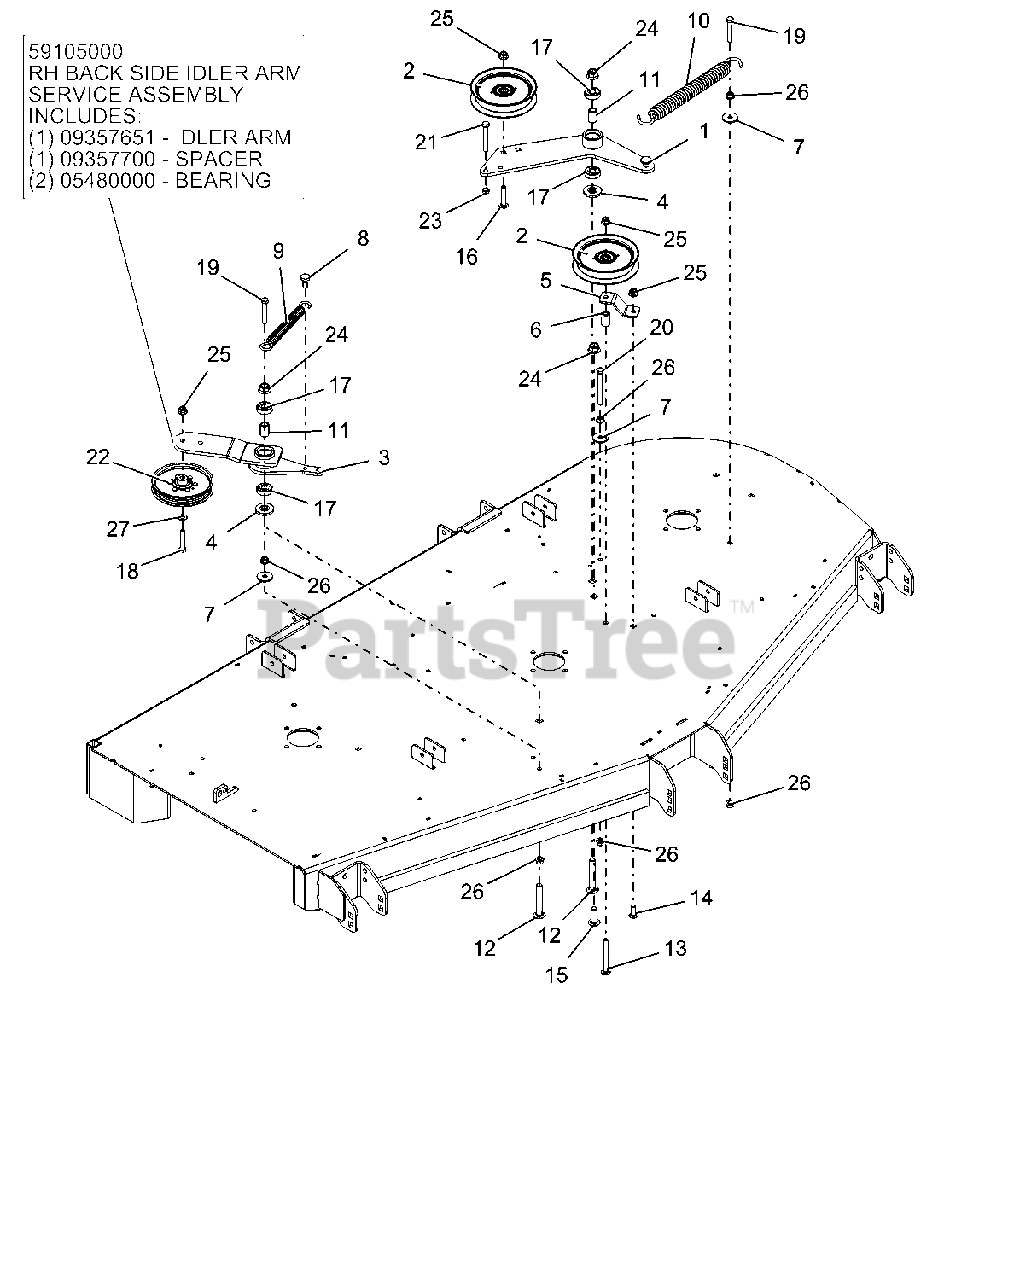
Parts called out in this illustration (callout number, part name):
1	DECK PTO IDLER ARM WLDMT - BLK
2	IDLER, FLAT 5.00"
3	BRG-BALL .50X1.38X.438 SEALED
3	SPACER .510 X .75 X 1.1485
3	DECK RH IDLER ARM WMT - BLK
3	RH BACKSIDE IDLER ARM ASSEMBLY
4	SPACER, IDLER ARM
5	PTO FIXED IDLER MTG BRKT -RED
6	BUSHING, SLV .380X.750X1.190
7	WSHR-FL-STL .406X1.375X.135 YZ
8	BLT,SHLDR EP .38-16X.30 HEX YZ
9	SPRING, EXTENSION
10	SPRING, EXTENSION
11	SPACER .510 X .75 X 1.1485
12	BLT,RDHDSQSHNK.50-13X3.25 G5YZ
13	BLT-RHDSSQNK .38-16X3.50 G5YZ
14	BLT-RDHDSHSQNK.38-16X1.0 G5YZ
15	BLT-RDHDSHSQNKFT.50-13X1.50 G5
16	BLT-RDHDSQNK .38-16X2.00 SHTYW
17	BRG-BALL .500X1.38X.437
18	BLT-HEX .38-16X2.00 GR5 YWZC
19	BLT-HEX .38-16X2.25 GR5 YWZC
20	BLT-HEX .38-16X3.50 GR5 YWZC
21	BLT-HEX .38-16X2.75 GR5 YWZC
22	PULLEY, FLAT IDLER
23	NUT-HEX-JAM .375-16 YWZC
24	NUT-LK-NYL-FLG .50-13 YWZC
25	NUT-LK-NYL-FLG .38-16 YWZC
26	NUT-SPNLK-FLG .375-16 YWZC
27	WSHR-FL-STL.406X.812X.065 YWZ
